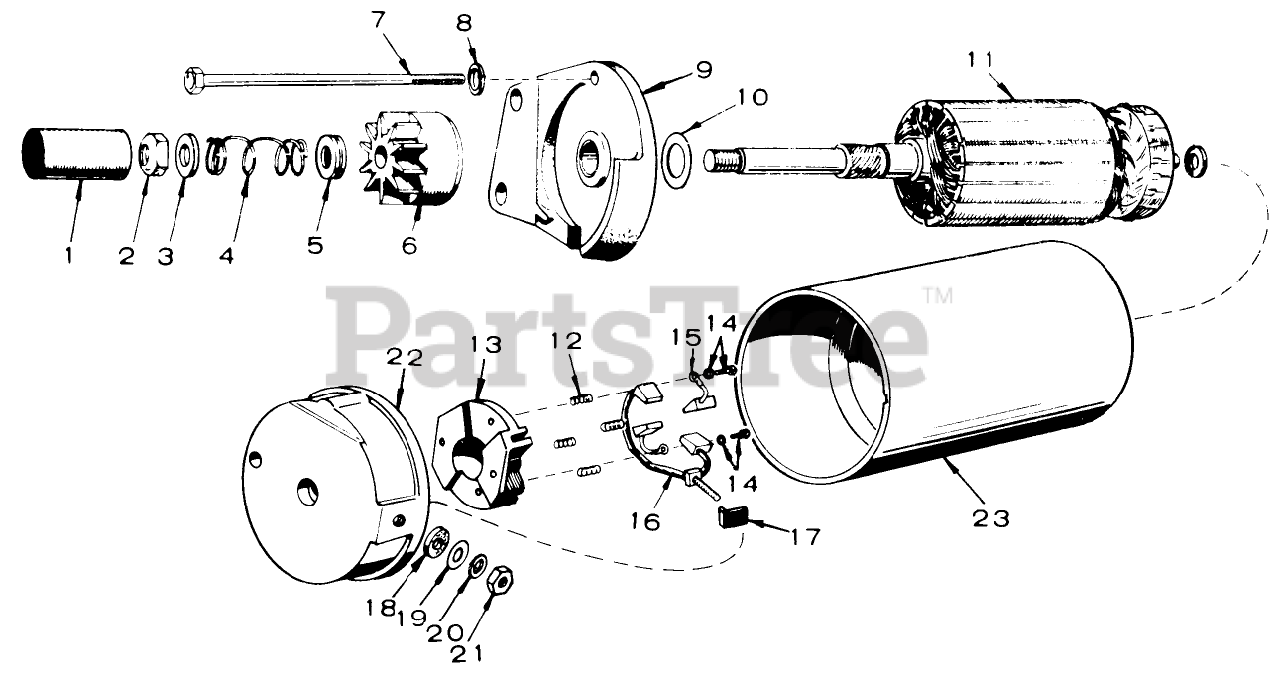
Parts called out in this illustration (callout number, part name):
8	Lock Washer
12	?*Spring, Brush
13	?Brush Holder
14	?Screw and Lockwosher-Brush and Brush Holder Mounting
15	?*Brush, Ground
16	?*Stud and Brush Assembly Input
17	?Bushing, Insulotion-Input Stud
18	?Washer, Insulation-Input Stud
19	?Washer, Flat-Input Stud
20	?Washer, Lock-Input Stud
21	?Nut, Securing-Input Stud
23	Housing, Starter Motor
